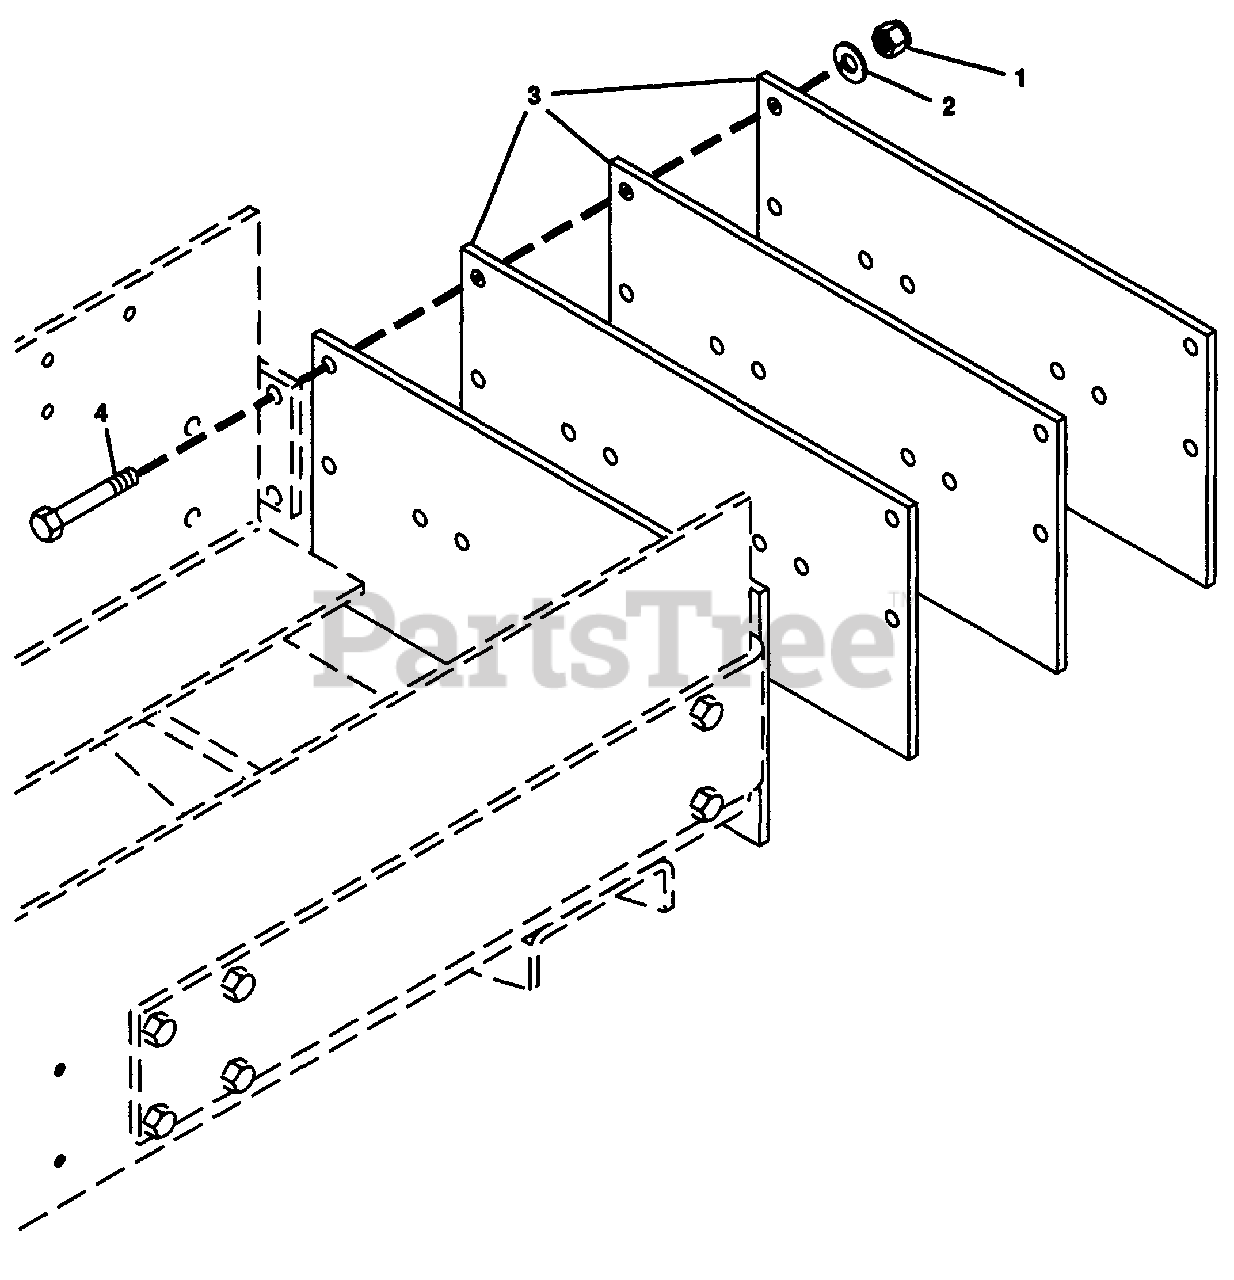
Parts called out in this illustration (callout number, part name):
1	Nut, Lock 1/2-13
2	Washer, Flat .531x1.062x.095
3	Plate, Bumper
4	Bolt, Hex 1/2-13x2.75
